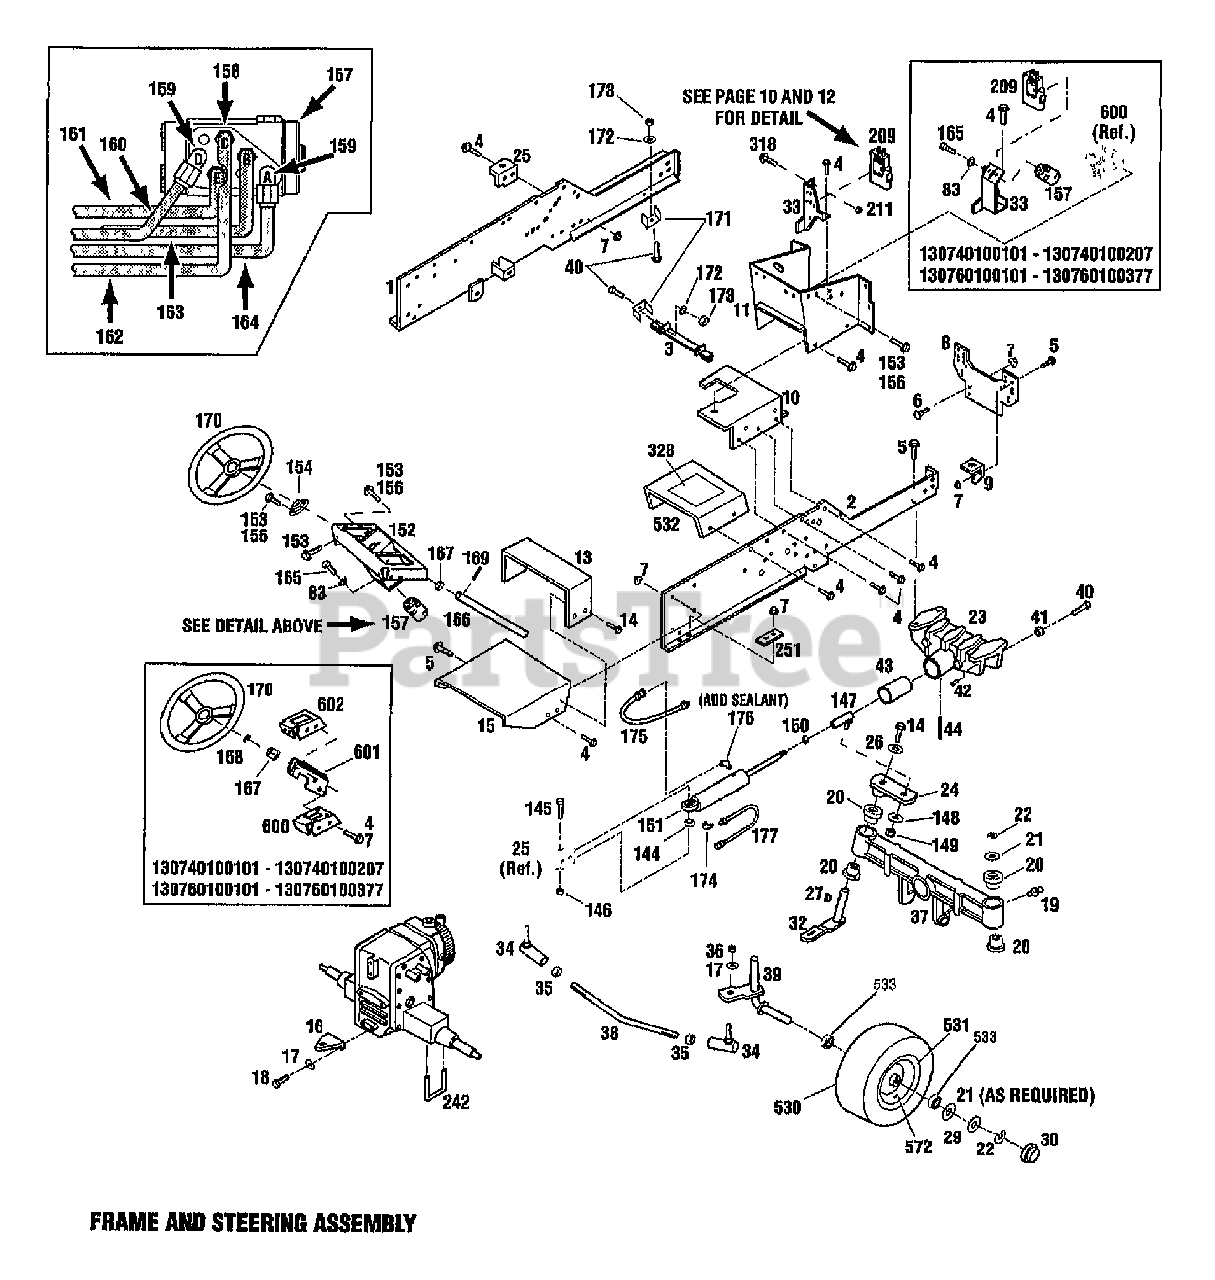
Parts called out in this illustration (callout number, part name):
3	ASSM-FRAME SUPPORT
5	SCR-HFLK 3/8-16X1.00 ZP
6	SCR-CARR 3/8-16X.75 G5 ZP
7	NUT-HFLK 3/8-16 ZP
8	PLATE-FRONT
9	SUPPORT-ENGINE
10	SUPT-BATTERY ASSM
11	SUPPORT
13	SUPPORT-FENDER
14	SCR-HFLK 5/16-18X.75 ZP
15	SUPPORT-FUEL TANK
16	HITCH-DRAWBAR
17	WASHER-LK .5
18	SCR-HH 1/2-13X1.25 G5 ZP
19	FITTING-GREASE 1/4-28X2.00
20	BEARING-FLANGE
21	WASHER-THRUST
22	RING-HEAVY EXT HD 1.0 ID
23	BOLSTER-FRONT AXLE
24	ARM-STEERING
25	BRKT-CYLINDER
26	WASHER-1.75X.328X.1345
27	KEY-WOODRUFF .25X.875
29	WASHER-SPECIAL .75X2.5
30	CAP-HUB
32	SPINDLE-WHEEL LEFT
33	SUPPORT-VALVE
33	SUPPORT ASSM-VALVE
34	JOINT-BALL
35	NUT-JAM
36	NUT-H/LK 1/2-20 ZP
37	AXLE-FRONT
38	ROD-TIE
39	SPINDLE-WHEEL RH
40	SCR-HH 5/16-18X1.0 G5 ZP
41	NUT-HEX JAM 5/16-18
42	PIN-WELD
43	TUBE-PIVOT AXLE
44	PIN-.312X.75
83	WASHER-LK .25 ZP
144	SLEEVE-CYLINDER
145	SCR-HH 5/8-11X3.0 G5
146	NUT-LOCK
147	JOINT-BALL
148	WASHER-LK 1.072X.634X.156
149	NUT-LK TOP 5/18-18
150	NUT-HEX/JAM 5/8-18 ZP
151	CYLINDER-HYDRAULIC
153	SCR-HFLK 5/16-18X.62 G5ZP
154	BRG-FLANGE
156	NUT-HFLK 5/16-18 ZP
157	CONTROL UNIT
158	CONNECTOR
159	ELBOW
160	TUBE-HYD RIGHT
161	TUBE-HYD PB VALVE
162	TUBE-HYDRO PRESSURE
163	TUBE-HYD LEFT
164	TUBE-HYD S C U TANK
165	SCR-HH M6-1.0X19MM
166	SHAFT-STEERING
167	BEARING-FLANGED NYLON
167	COLLAR
168	RING-RET."E".577 ID
169	PIN-DRIVE .25X1.5
170	WHEEL-STEERING
171	CLAMP
172	WASHER-LK .312 ZP
173	NUT-HEX 5/16-18 ZP
174	ELBOW
175	ASSM-HOSE
176	ELBOW
177	ASSM-HOSE
209	VALVE-HYDRAULIC
211	NUT-HF/LK 1/4-20 ZP
242	BOLT-U
251	DOUBLER-FRAME REAR
318	SCR-HH 1/4-20X.625
328	DECAL-OPERATING INST
530	TIRE-16X6.50-8
531	WHEEL
532	TUNNEL W/DECAL
533	BEARING-BALL
572	STEM-VALVE
600	BRKT-STEERING
601	SUPPORT-STEERING
602	STEERING BRACKET
